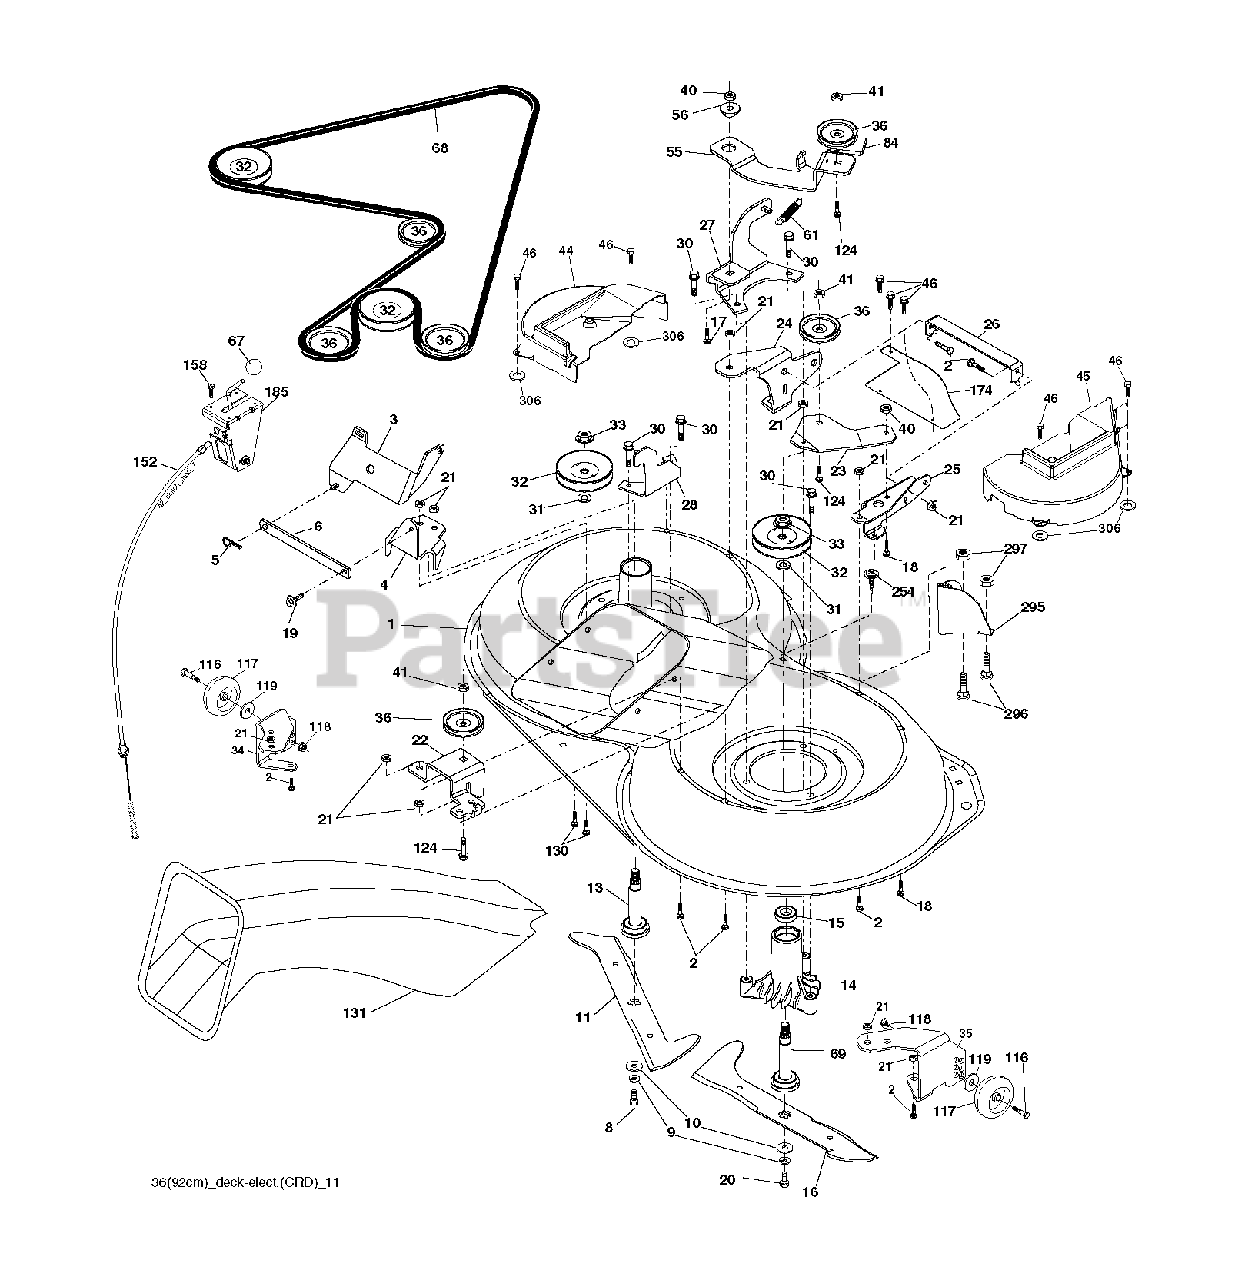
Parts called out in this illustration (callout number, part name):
2	BOLT
3	BRACKET.ASM.BAR.SWAY.CHASS
5	RETAINER-SPRNG RB
6	BAR SWAY
9	LOCKWASHER
10	WASHER.BLADE
13	SHAFT ASM VENT
14	HSG MANDREL
17	BOLT.3/8-14X1.25
19	BOLT SHD 5/16-18
21	LOCKNUT
24	BRACKET
25	BRACKET
28	BRACKET
30	SCREW, WASHER HEAD
31	WASHER.SPACER.MANDREL
32	PULLEY MANDREL
33	NUT.FLANGE.LOCK.TOP
36	PULLEY.IDLER.4.25
40	LOCKNUT
41	NUT LOCK FLG 3/8-16 UNC
46	SCREW.1/4-20X5/8
56	SPACER.RETAINER.MOWER
67	KNOB T (3/8 HOLE)
69	SHAFT.ASM.W/LWR.BRG.RH.THREAD
84	KEEPER, BELT IDLER
116	BOLT.SHOULDER.3/8-16X3-5/8
117	WHEEL. GUAGE RALLY
118	NUT LOCK FLG 3/8-16 UNC
124	BOLT.3/8-16X1.50
131	CHUTE BAGGER
158	SCREW
185	HEAD ASM. CABLE CLUTCH
254	SCREW 3/8-16X1
296	BOLT
297	NUT CENTERLOCK
306	PALNUT 1/4
